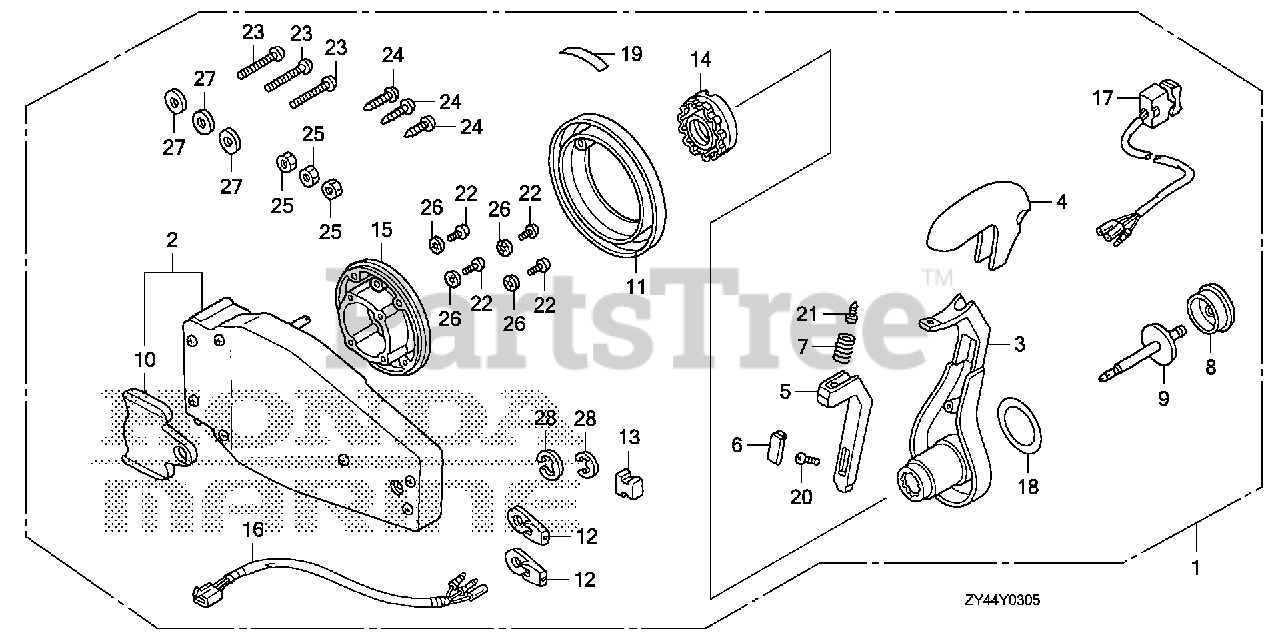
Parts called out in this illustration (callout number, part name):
1	BOX KIT, REMOTE CONTROL (FLUSH MOUNT)(L)
2	HOUSING ASSY., L. (INNER) (FLUSH MOUNT)
3	HANDLE, REMOTE CONTROL
4	COVER, GRIP
5	ARM, NEUTRAL LOCK
6	COVER, LOCK ARM
7	SPRING, NEUTRAL LOCK ARM
8	BUTTON, THROTTLE
9	SHAFT, THROTTLE BUTTON
10	PLATE, DWELL
11	COVER ASSY.
12	TERMINAL, CABLE
13	SPACER, CABLE CLAMP
14	HOLDER, NEUTRAL LOCK
15	BASE
16	SUB-HARNESS ASSY., POWER TRIM-TILT (C)
17	SWITCH ASSY., POWER TRIM-TILT (C)
18	MARK, HANDLE FLUSH MOUNT
19	MARK, FLUSH MOUNT
20	SCREW, TRUSS (4X12)
21	SCREW, PAN (5X16)
22	SCREW, PAN (5X30)
23	SCREW, PAN (6X35)
24	SCREW, TAPPING (6X30)
25	NUT, HEX. (6MM)
26	WASHER, LOCK (5MM)
27	WASHER, PLAIN (6MM)
28	E-RING (6MM)
